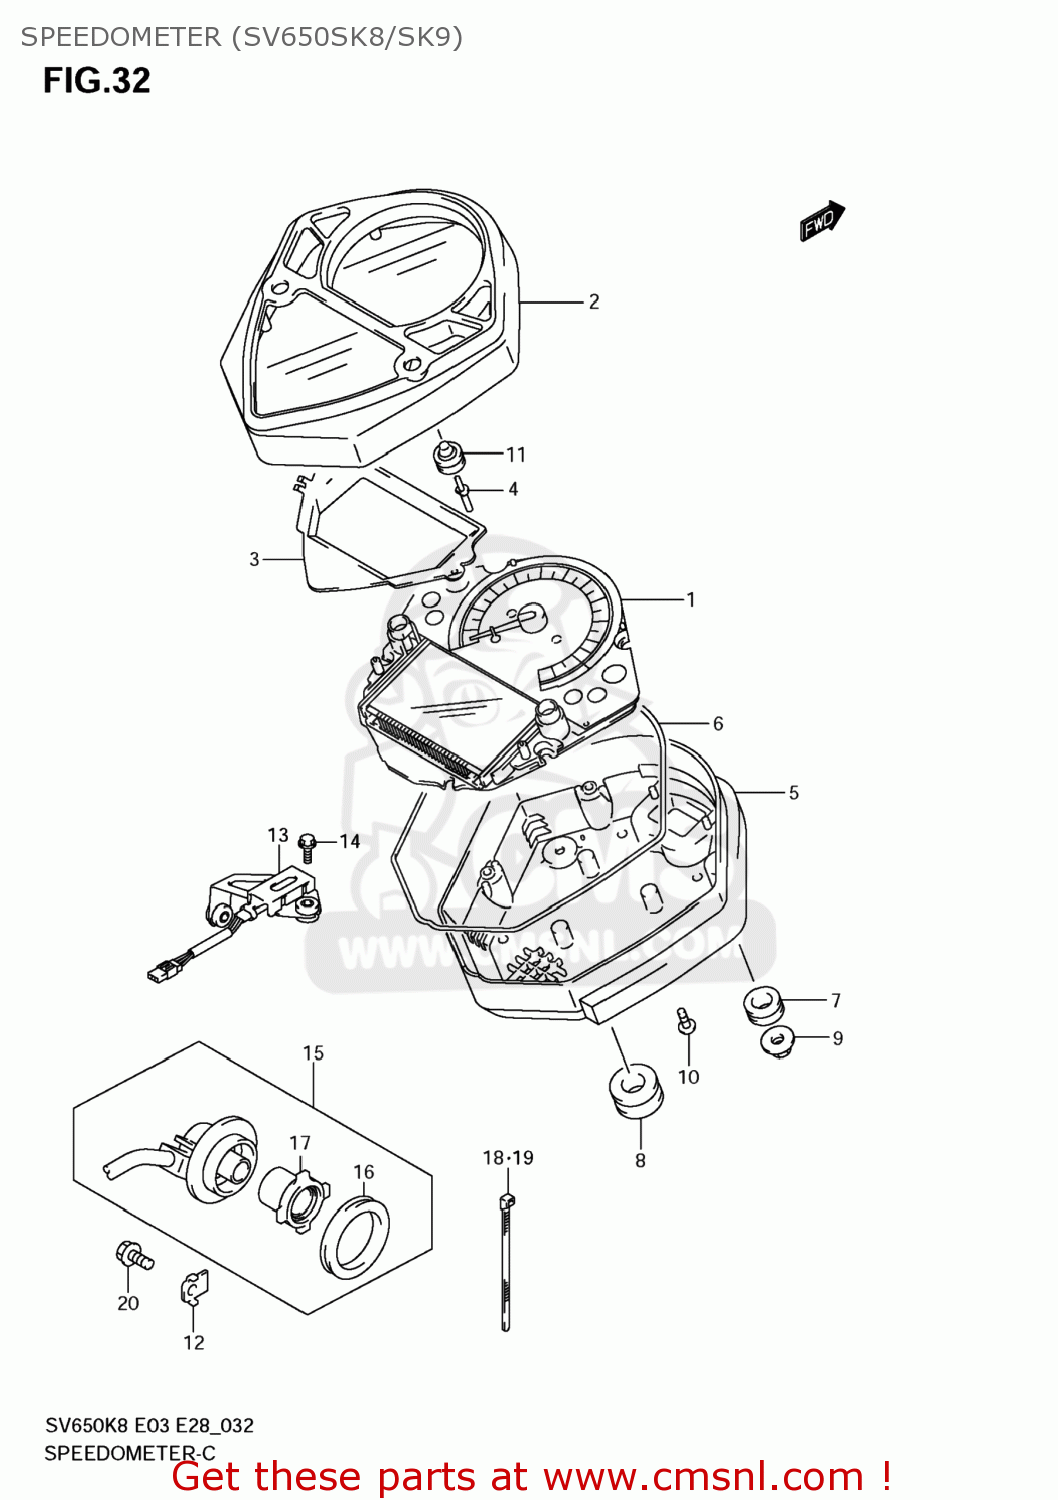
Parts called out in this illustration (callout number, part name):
1	SPEEDOMETER
2	CASE,SPEEDOMETER UPR
3	PLATE,SPEEDOMETER
4	KNOB,SPEEDOMETER
5	CASE,SPEEDOMETER LWR
6	GASKET,METER CASE (NAS)
7	CUSHION
8	CUSHION
9	NUT
10	SCREW,SPEEDOMETER
11	COVER,SPEEDOMETER KNOB
12	GUIDE,SENSOR LEAD
13	RESISTOR ASSY
14	BOLT(6X25)
15	SENSOR,SPEED
16	SEAL,OIL(44X55X6)
17	MAGNETO
18	CLAMP(L:100)
19	CLAMP(L:125)
20	BOLT
